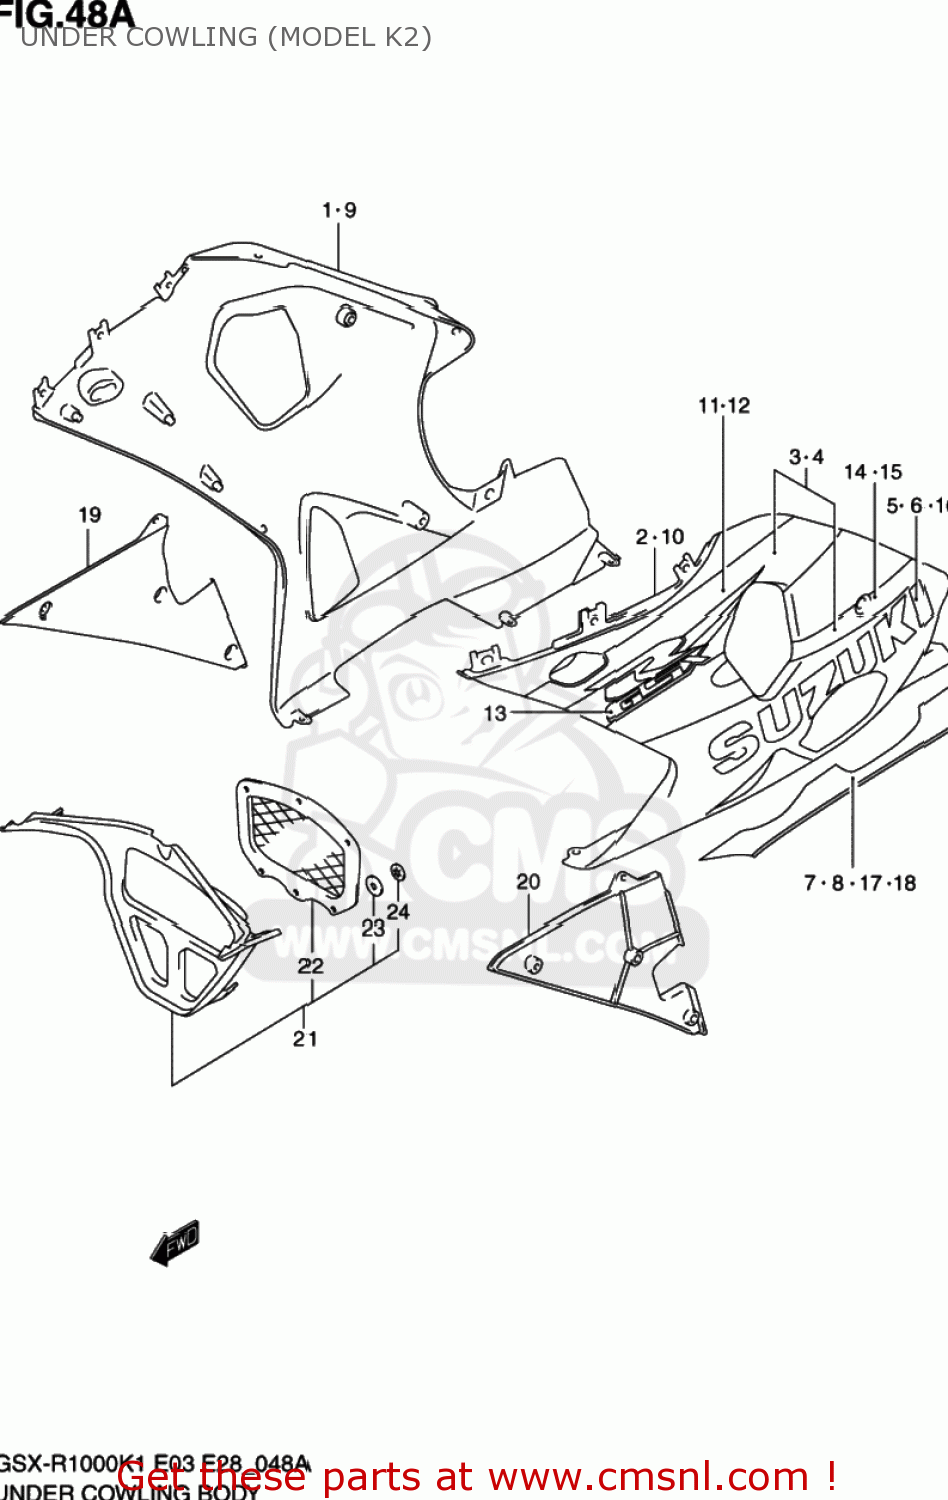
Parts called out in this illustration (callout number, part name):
1	COWLING ASSY,UNDER,R
2	COWLING ASSY,UNDER,L
3	TAPE,UNDER UPR,R
4	TAPE,UNDER UPR,L
5	EMBLEM,UNDER,SUZUKI,R
6	EMBLEM,UNDER,SUZUKI,L
7	TAPE,COWL LWR,R
8	TAPE,COWL LWR,L
9	COWLING ASSY,UNDER,R
10	COWLING ASSY,UNDER,L
11	TAPE,COWL UPR,R
12	TAPE,COWL UPR,L
13	EMBLEM,UNDER,GSX
14	TAPE,COWL MIDDLE,R
15	TAPE,COWL MIDDLE,L
16	EMBLEM,UNDER,SUZUKI,R
17	TAPE,COWL LWR,R
18	TAPE,COWL LWR,L
19	COWLING,UNDER INNER,R
20	COWLING,UNDER INNER,L
21	COWLING,UNDER CTR
22	NET,UNDER COW CTR
23	CUSHION
24	NUT
